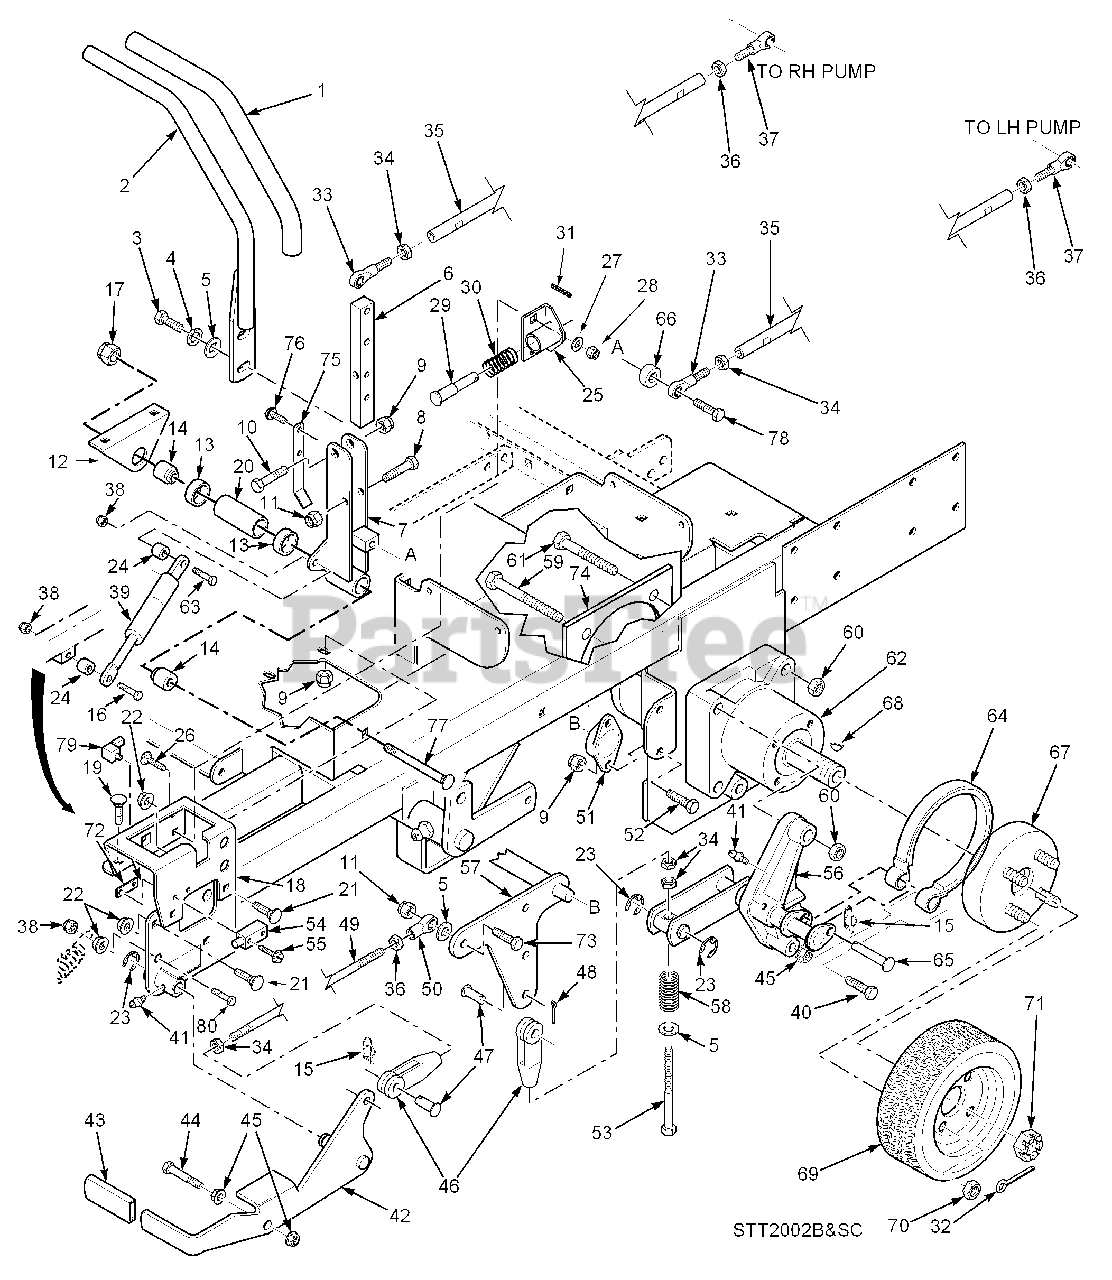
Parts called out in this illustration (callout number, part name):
1	Grip, Handle Bar
2	Handle Bar
3	Bolt, Hex Head 3/8-16 x 1-1/4"
4	Lockwasher, 3/8"
5	Flatwasher. 3/8"
6	Bar, Control Lever
7	Control Lever Weldment, LH
8	Bolt, Hex Head 5/16-18 x 2"
9	Nut, Hex Elastic Stop 5/16-18
10	Bolt, Hex Head 3/8-16 x 2"
11	Nut, Hex Elastic Stop
12	Mount, Control Linkage
13	Ball Bearings, Neutral Return
14	Spacer
15	Pin, Rue Cotter 3/8 Dia.
16	Bolt, Hex Head, 5/16-18 x 2.75 Zinc.
17	Nut, Hex Elastic Stop 5/8-11
18	Bracket, Control Lever LH
19	Bolt, Carriage 5/16-18 x 1"
20	Spacer, Bearing
21	Bolt, Carriage 5/16-18 x 3/4"
22	Nut, Hex Serrated Flange 5/16-18
23	Ring, Retaining 5/8" External "E"
24	Spacer
25	Bracket, Neutral Return
26	Bolt, Carriage 1/4-20 x 3/4"
27	Flatwasher, 1/4"
28	Nut, Hex Elastic Stop 1/4-20
29	Pin, Retaining Spring
30	Spring
31	Roll Pin, Spring 5/32 x 3/4"
32	Pin, Cotter 9/16 x 1-1/2"
33	Rod End, Male 3/8-24 RH Thread
34	Nut, 3/8-24 RH Thread
35	Tube, Control Link Air Cooled Engine
36	Nut, Hex 3/8-24 LH Thread
37	Rod End, Male 3/8-24 LH Thread
38	Locknut, 5/16-18, Elastic Stop
39	Gas Damper
40	Bolt, Hex Head 3/8-16 x 2-1/2"
41	Grease Fitting
42	Lever, Parking Brake
43	Grip, Parking Brake
44	Bolt, Hex Head 3/8-16 x 2-3/4"
45	Nut, Hex Serrated Flange 3/8-16
46	Clevis, Traction Control
47	Pin, Clevis 3/8-16 x 1-1/16"
48	Pin, Cotter 3/32 x .75
49	Rod, Parking Brake
50	Rod End, LH Thread
51	Bushing, Self Align
52	Bolt, Hex Head 5/16-18 x 3/4"
53	Bolt, Hex Hd 3/8-24 x 5-1/4", 23/4" Thrd
54	Switch
55	Screw, Hex SLTD WSHR Head #10 32 x 3/4"
56	Brake Linkage, LH
57	Bellcrank, Brake Actuator
58	Spring
59	Bolt, Hex Head 1/2-13 x 3-3/4"
60	Locknut, Hex 1/2-13 Center Lock
61	Bolt, Hex Head 1/2-13 x 2-1/2"
62	Wheel Motor, Ross
63	Bolt, Hex Head, 5/16-18 x 1.75, Zinc
64	Brake Band Assembly
65	Pin, Clevis 3/8" Dia. x 1.93"
66	Spacer
67	Wheel Hub/Brake Drum Assembly
68	Key, Woodruff 5/16 x 1"
69	Wheel Assembly 23 x 10.5-12
69	Rim W/Valve Stem
69	Tire, 23 x 10.5-12
69	Wheel Assembly 24 x 12-12 Turf Master
69	Tire, 24 x 12-12 Turf Master
70	Lug Nut, 1/2-20
71	Nut, Hex Castle
72	Threaded Plate
73	Bolt, Hex Head 3/8-16 x 1-1/2"
74	Plate Weldment, Motor Backing
75	Actuator Switch
76	Bolt, Hex Serrated Flange 5/16-18 x 3/4"
77	Bolt, Carriage 3/8-16 x 4-3/4"
78	Bolt, Hex Head 3/8-16 x 1"
79	Switch
80	Bolt, Hex Head 3/8-16 x 1-1/4" Grade 8
